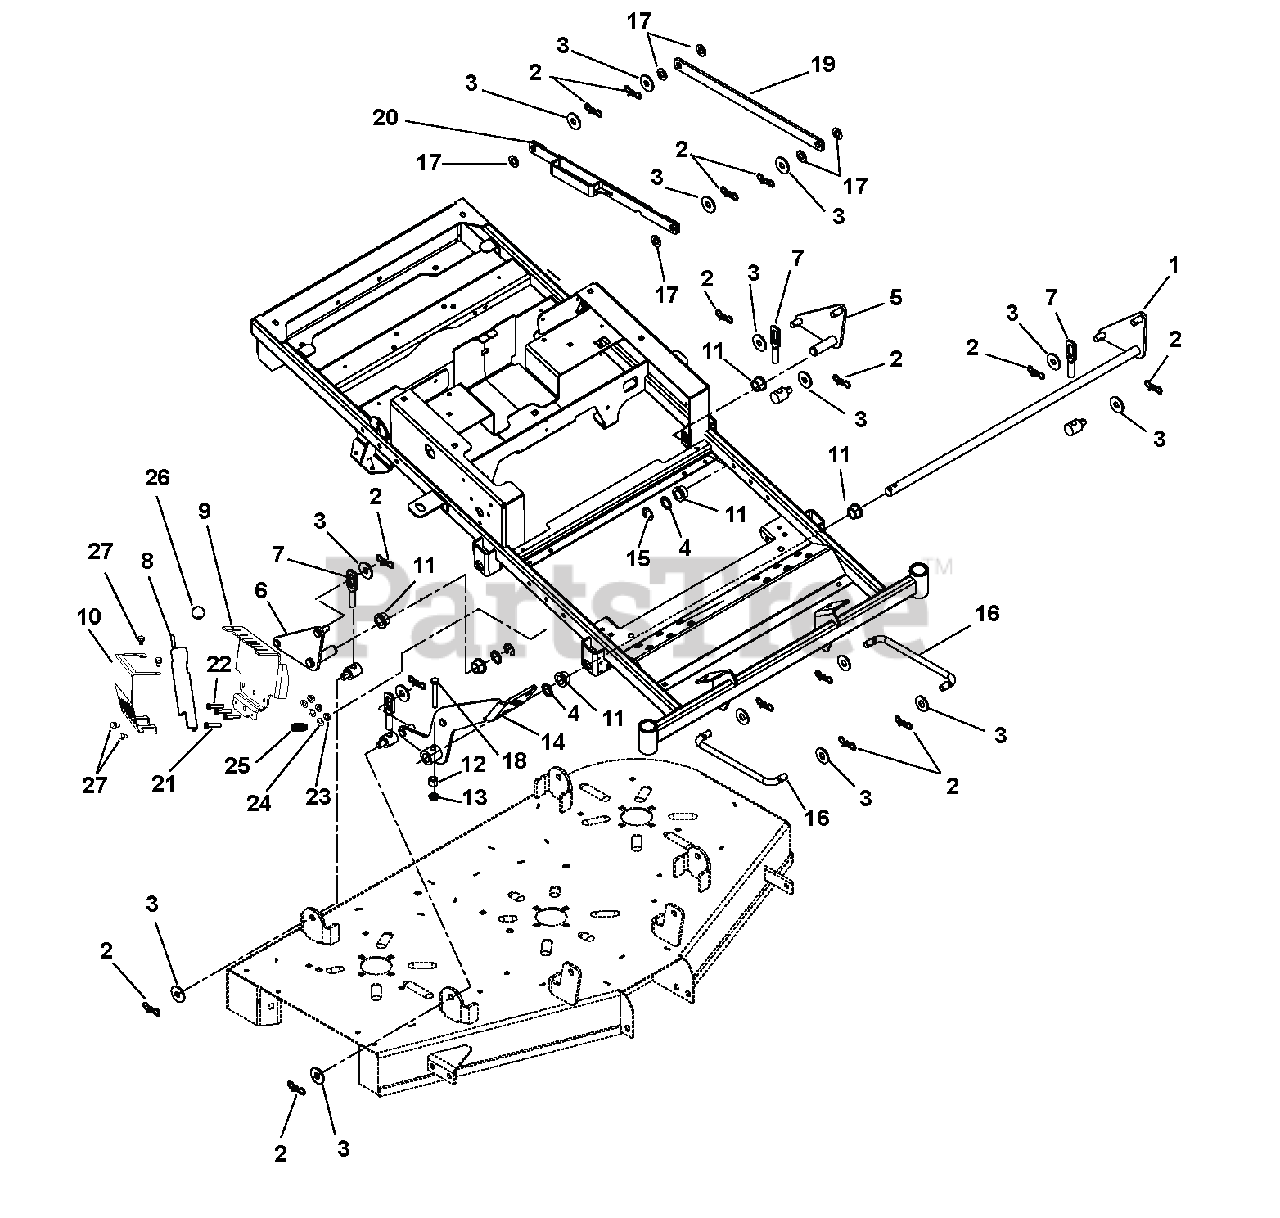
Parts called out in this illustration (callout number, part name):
1	WMT-DECK PIVOT FRONT
2	PIN,BOW TIE LOCKING .091X1.875
3	WSHR-FL-STL.511X1.441X.125 YWZ
4	WSHR-FL-STL.754X1.125X.062YWZC
5	WMT-DECK PIVOT ZTXL REAR LH
6	WMT-DECK PIVOT ZTXL REAR RH
7	ASM, DECK LINK
8	LEVER, HOC WLDMT XL
9	BRACKET, ADJUSTER HOC XL
10	GUARD, PLATE FIXED
11	BSHG-FLG .750X1.000X.625X1.250
12	BSHG-SLV .391X.688X.52 PM
13	@NUT-LK-NYL-FLG .38-16 YWZC
14	WMT-ZTXL FOOT PEDAL
15	RG-RTNG-EXT .750X.050
16	LINK, DRAG
17	WSHR-FL-NYL .518X1.000X.080
18	@BLT-HEX .38-16X2.50 GR5 YWZC
19	LINK, LIFT
20	HOC, LINK RETAINING XL
21	@BLT-HEX .38-16X2.25 GR5 YWZC
22	@BLT-HEX .38-16X1.75 GR5 YWZC
23	@NUT-LK-NYL-FLG .38-16 YWZC
24	@WSHR-FL-STL.38X.875X.083 YWZC
25	SPRING, COMPRESSION
26	KNOB,BALL -BLACK 1.47" .375-16
27	SCR-TAP .25-20X.50 HWH TR YWZ
